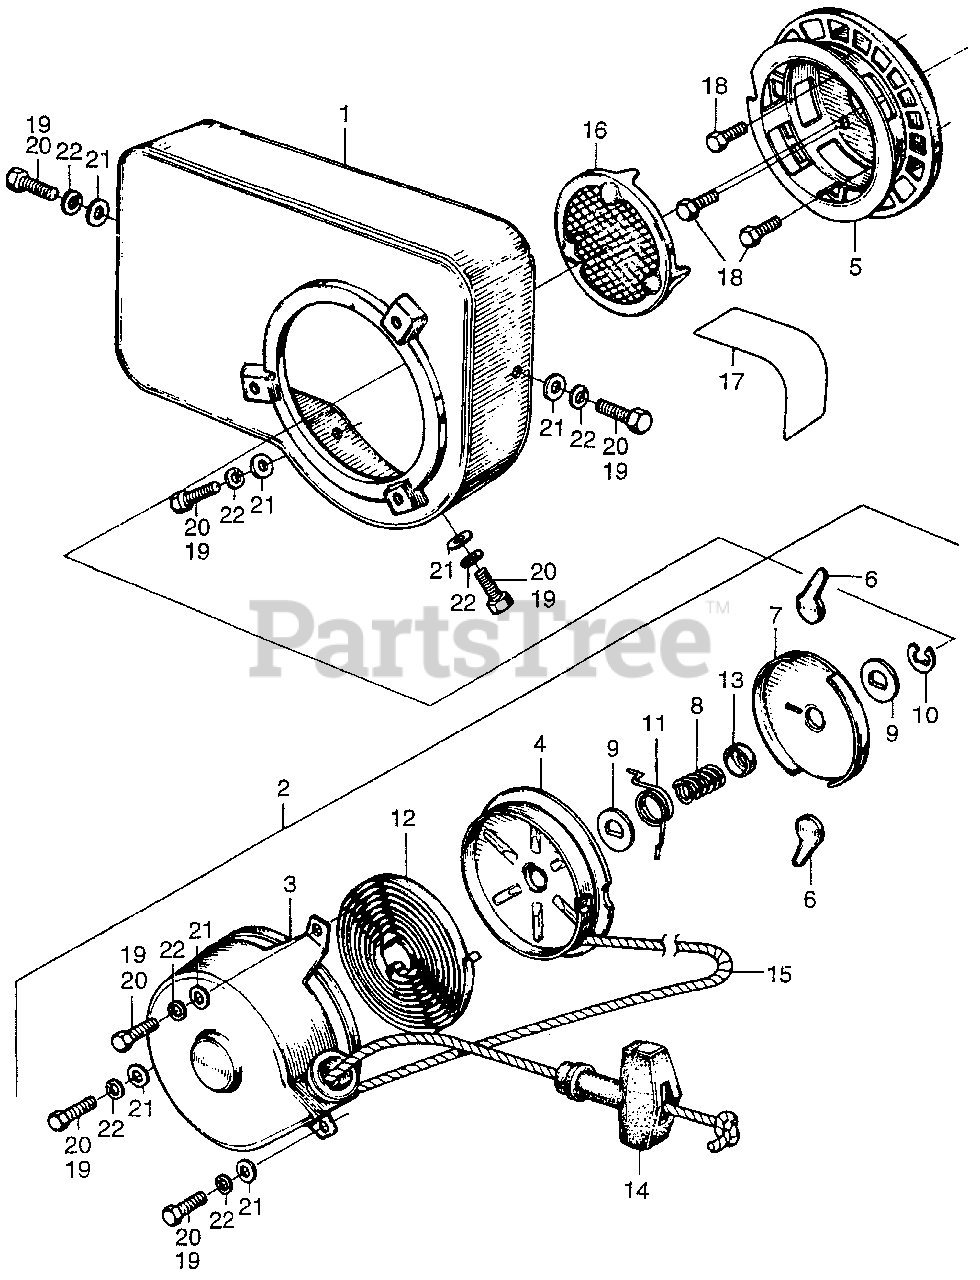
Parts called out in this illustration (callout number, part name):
1	COVER, FAN *R8* (BRIGHT RED)
2	STARTER, RECOIL *R8* (BRIGHT RED) (NOT AVAILABLE)
3	CASE, STARTER *R8* (BRIGHT RED) (NOT AVAILABLE)
4	PULLEY, STARTER (NOT AVAILABLE)
5	PULLEY, RATCHET (NOT AVAILABLE)
6	RATCHET, STARTER
7	PLATE, FRICTION
8	SPRING, FRICTION (NOT AVAILABLE)
9	WASHER, STARTER
11	SPRING SET
12	SPRING, STARTER
13	COVER, SPRING
14	KNOB, STARTER
15	ROPE, RECOIL STARTER (#5X55")
16	SCREEN, CENTER
18	BOLT, HEX. (5X8)
20	BOLT, HEX. (6X12)
21	WASHER, PLAIN (6MM)
22	WASHER, SPRING (6MM)
